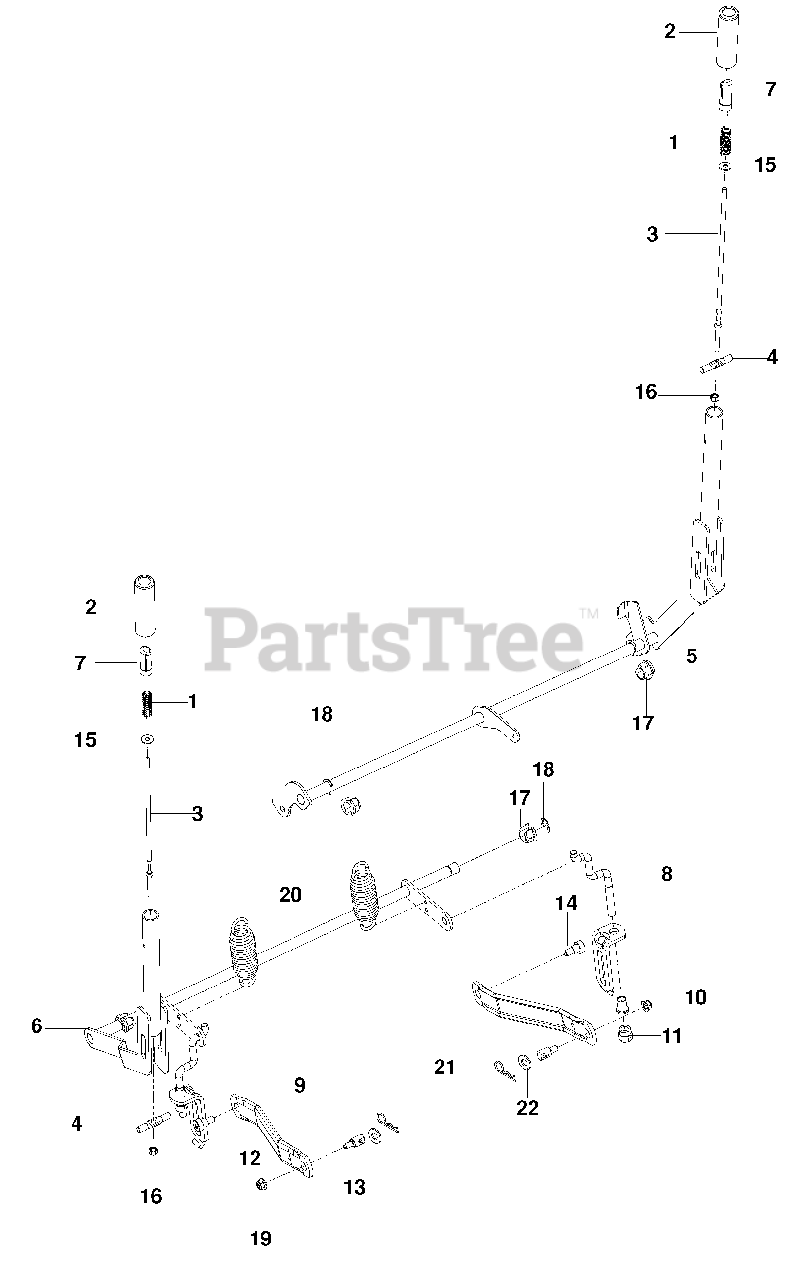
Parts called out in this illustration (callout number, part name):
1	SPRING, COMPRESSION
2	GRIP, HANDLE
3	ROD, HANDLE RELEASE
4	ROD, LATCH RELEASE
5	SHAFT, BRAKE
6	ARM, LIFTING
7	BUTTON, PUSH
8	LINK, REAR SUSPENSION
9	BRACKET, LIFT
10	BUSHING, ALIGNMENT
11	NUT, LIFT LINK
12	ARM, SUSPENSION RR
13	STUD, w/ANTI- ROTATE
14	SB 3/8-16 x 3/8 SKT HD
15	WASHER 1/4 FLAT
16	NUT 1/4 -20 HEX NYLOC
19	NUT 5/16-18 FLANGE NYLOC
21	HAIRPIN #4
22	WASHER 5/8 FLAT SAE
